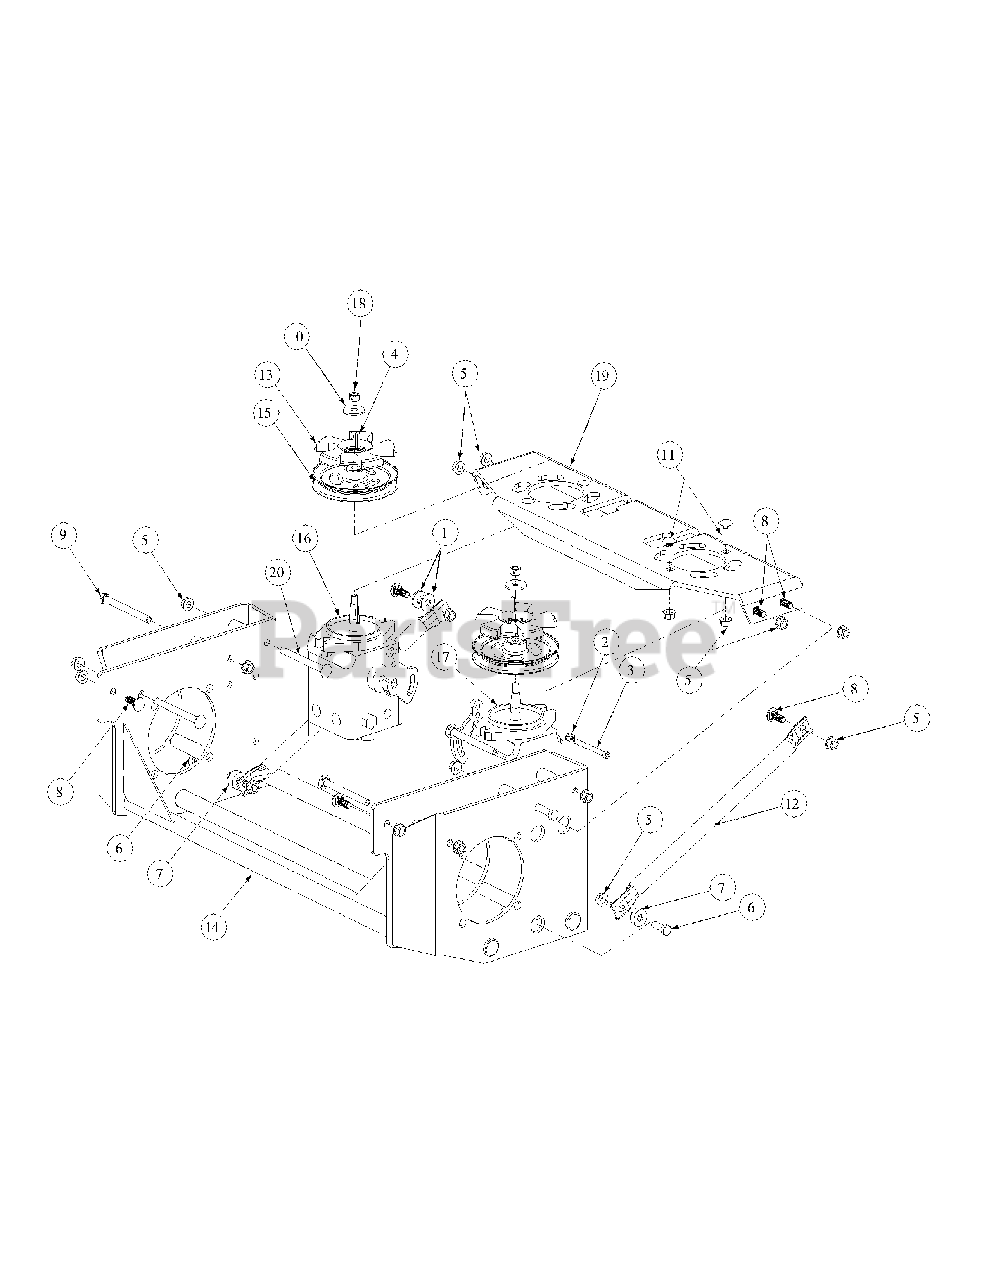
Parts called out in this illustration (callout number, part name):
1	Washer lock 3/8 zinc
2	Lock Nut, Nylon Insert, 1/4-20
3	Socket Head Cap Screw, 1/4-20 x 2-1/2
4	Key, 3/16" x 7/8"
5	Flange Lock Hex Nut, 3/8-16
6	Hex Cap Screw, 3/8 -16 x 1.25
7	Spacer, .406 ID x 1.00 OD x .38
8	Carriage Bolt, 3/8-16 x 1
9	Hex Cap Screw, 3/8-16 x 4.00
10	Flat Washer, .411 x 1.25 x .100
11	Carriage Screw, 3/8-16 x 1.25
13	Hydro Pulley Fan
14	Hydro Motor Frame Assembly
15	Hydro Pump Pulley
16	Hydro Pump, LH
17	Hydro Pump, RH
18	Hex Nut, 3/8-24
19	Hydro Pump Mount
20	Carriage Bolt, 3/8-16 x 4"
